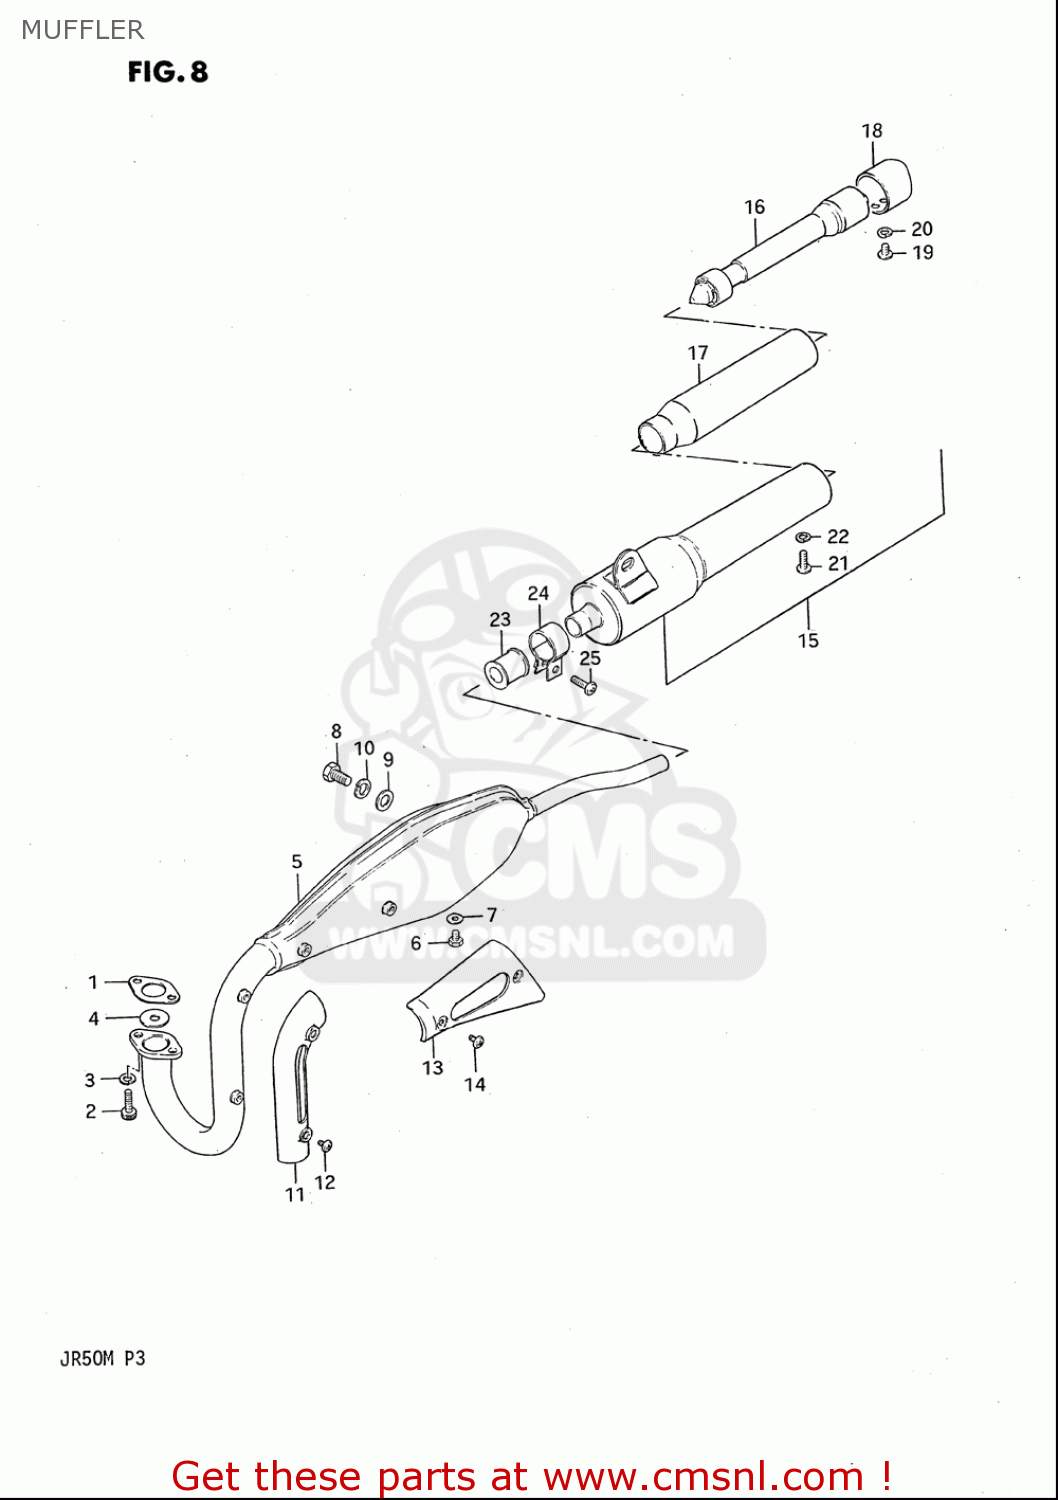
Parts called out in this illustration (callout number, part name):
1	GASKET,EXHAUST PIPE (NAS)
2	BOLT
3	WASHER,LOCK
4	PLATE,EXHAUST PIPE
5	MUFFLER ASSY
6	BOLT
7	WASHER
8	BOLT
9	WASHER(8.5X20X1.6)
10	WASHER,LOCK
11	COVER,EXHAUST PIPE
12	SCREW(5X6)
13	COVER,MUFFLER
14	SCREW(5X6)
15	MUFFLER ASSY,2ND
16	TUBE,CLEAN OUT
17	SHELL,ARRESTER
18	CUTTER,MUFFLER TAIL
19	SCREW
20	WASHER,LOCK
21	SCREW
22	WASHER,LOCK
23	CONNECTOR,MUFFLER
24	CLAMP
25	SCREW
